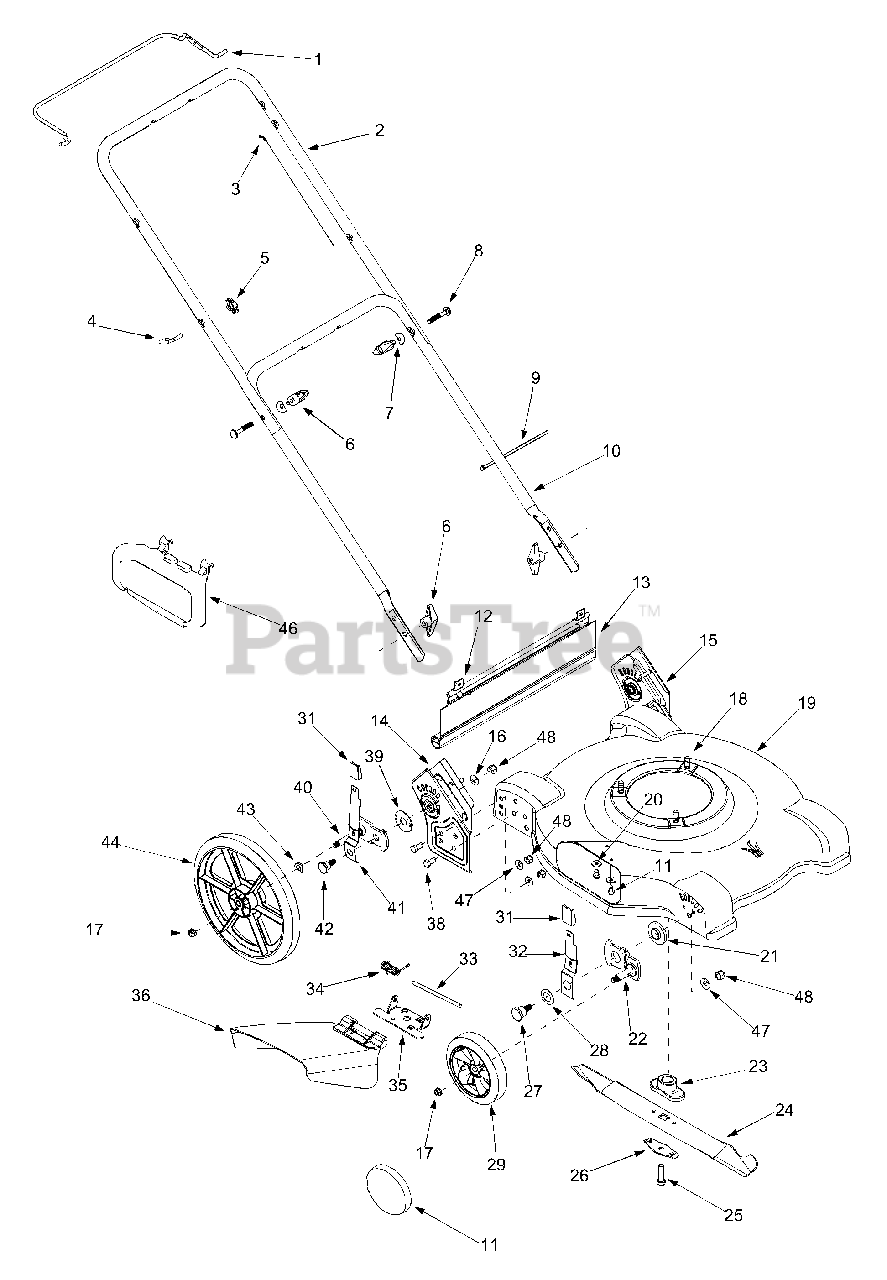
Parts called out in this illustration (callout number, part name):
3	Blade Control Cable - B&S 37.25" LG
4	Eye Bolt
5	Wing Nut
6	Wing Nut
7	Shoulder Washer .320 ID x .93 OD
8	Carriage Bolt 5/16-18 x 2.0
9	Cable Tie
11	Hub Caps (If Equipped)
12	Hinge Clip
13	Trail Shield
17	Lock Nut 3/8 -16
18	Hex Washer Screw 3/8-16 x 1.0
20	Bell Washer .265 x .75
21	Height Adjuster Bearing
22	Pivot Arm Assembly
23	Blade Adapter
24	Blade 22"
25	Hex Cap Screw 3/8-24 x 1.5
26	Blade Bell Support
27	Shoulder Screw 3/8 - 16 x .302
28	Bell Washer .760 ID x 1.25 OD
29	Front Wheel Assembly 7 x 1.8
31	Height Adjuster Knob
32	Front Spring Lever
33	Hinge Pin
34	Torsion Spring
35	Chute Hinge
36	Side Discharge Chute Assembly
38	Hex Cap Screw 3/8-16 x .75
39	Thrust Bearing .688 ID x 1.938 OD
40	Rear Pivot Arm Assembly
41	Rear Spring Lever
42	Shoulder Screw 3/8 - 16 x .442
43	Spring Washer
44	Rear Wheel Assembly 14 x 1.8
46	Snap Mulching Plug
47	Washer Spacer .401 ID x .870 OD
48	Hex Lock Nut 3/8-16
